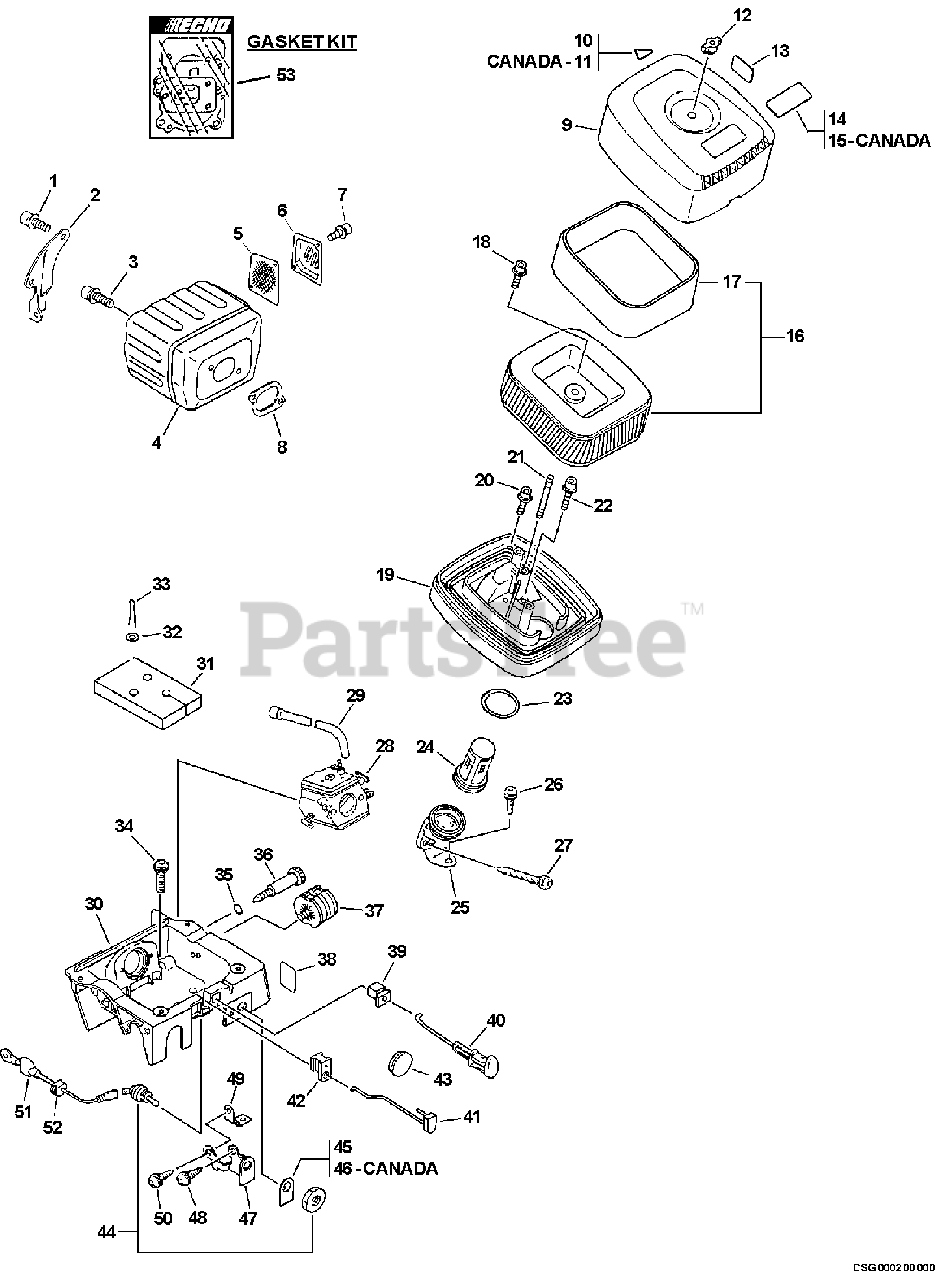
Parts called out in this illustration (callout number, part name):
1	BOLT 5×14
2	BRACKET, MUFFLER
3	BOLT 5×20
4	MUFFLER
5	SCREEN, SPARK ARRESTER
6	GUIDE, EXHAUST
7	BOLT 4×10
8	GASKET, EXHAUST
9	COVER, AIR FILTER
11	LABEL
13	LABEL, CAUTION
14	LABEL, MODEL
15	LABEL - MODEL CSG-670
16	FILTER, AIR
17	FILTER, AIR
18	BOLT - 5×16
19	CASE, AIR FILTER
20	SCREW 5×16
21	BOLT 5
22	SCREW 5×25
23	SEAL
24	SCREEN, FILTER
26	SCREW 5×14
27	SCREW 5×53
28	CARBURETOR - HDA-166A
29	PIPE, IMPULSE
30	CASE, CARBURETOR
31	PAD, FOAM
33	PIN, COTTER 3×18
34	BOLT 5×20
35	O-RING 7
36	SCREW, IDLE ADJUST - GRAY
38	LABEL, CAUTION - IDLE
39	GROMMET, CHOKE
40	ROD, CHOKE
41	ROD, THROTTLE
42	GROMMET, THROTTLE ROD
43	GROMMET, PLUG
44	SWITCH, ON-OFF
45	LABEL - SWITCH
46	LABEL - SWITCH
47	BRACKET, SWITCH
48	SCREW 5×10
49	PLATE, GROUND
50	SCREW 4×10
51	LEAD - GROUND
53	GASKET KIT
